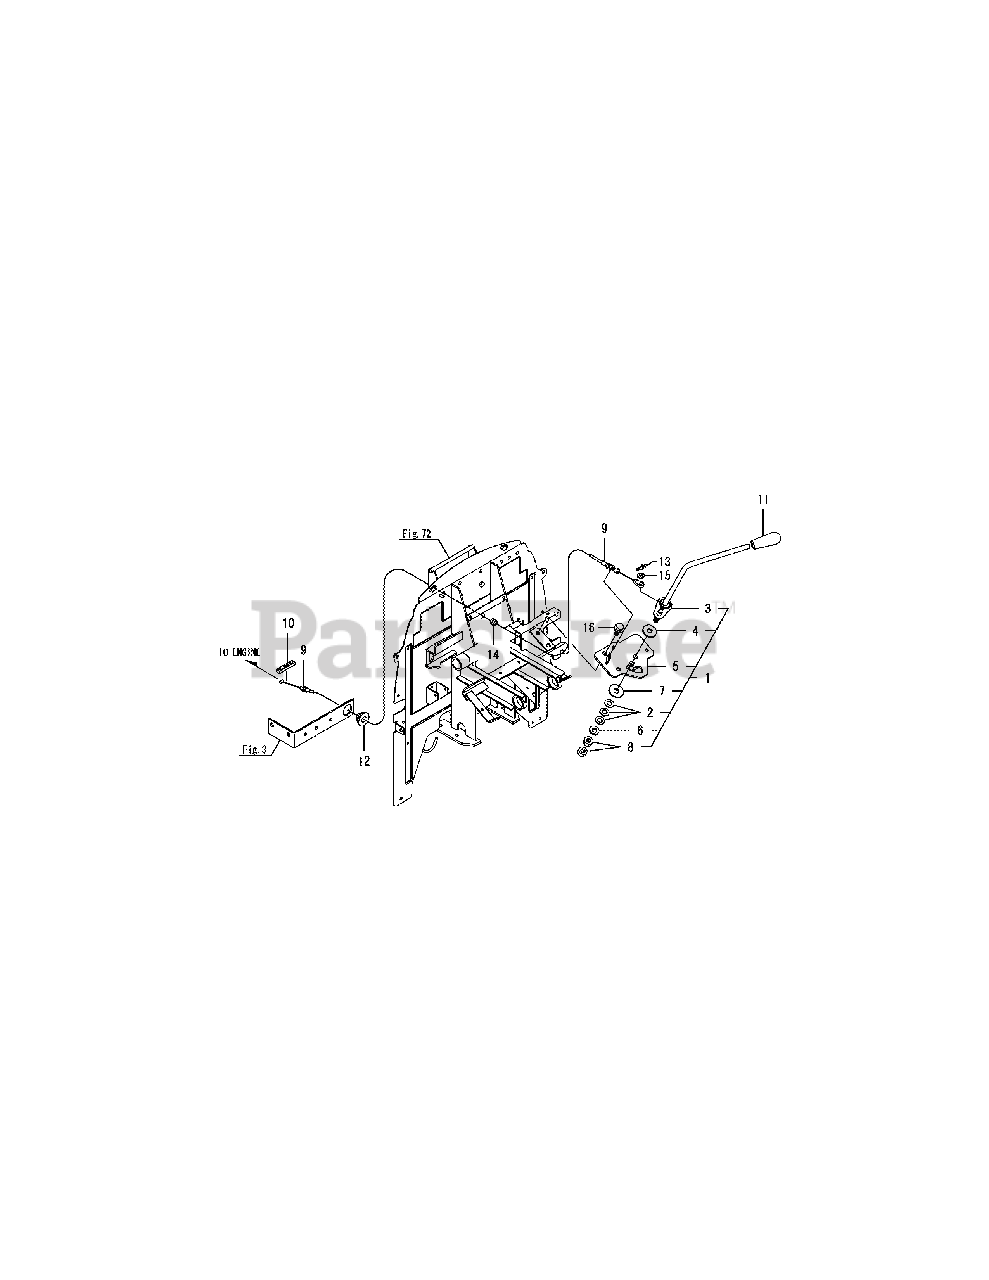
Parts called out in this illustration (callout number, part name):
1	LEVER ASSY, ACCEL
2	WASHER 10, CONICAL
4	PLATE, FRICTION
5	SUPPORT ASSY, ACCEL
6	WASHER 10,POLISHED
9	CABLE ASSY, HAND
10	RUBBER,WIRE RETAING
11	KNOB, THROTTLE LEVER
13	PIN 6,COME-OFF SNAP
15	WASHER 6, POLISHED
16	BOLT M 8X 16 PLATED
